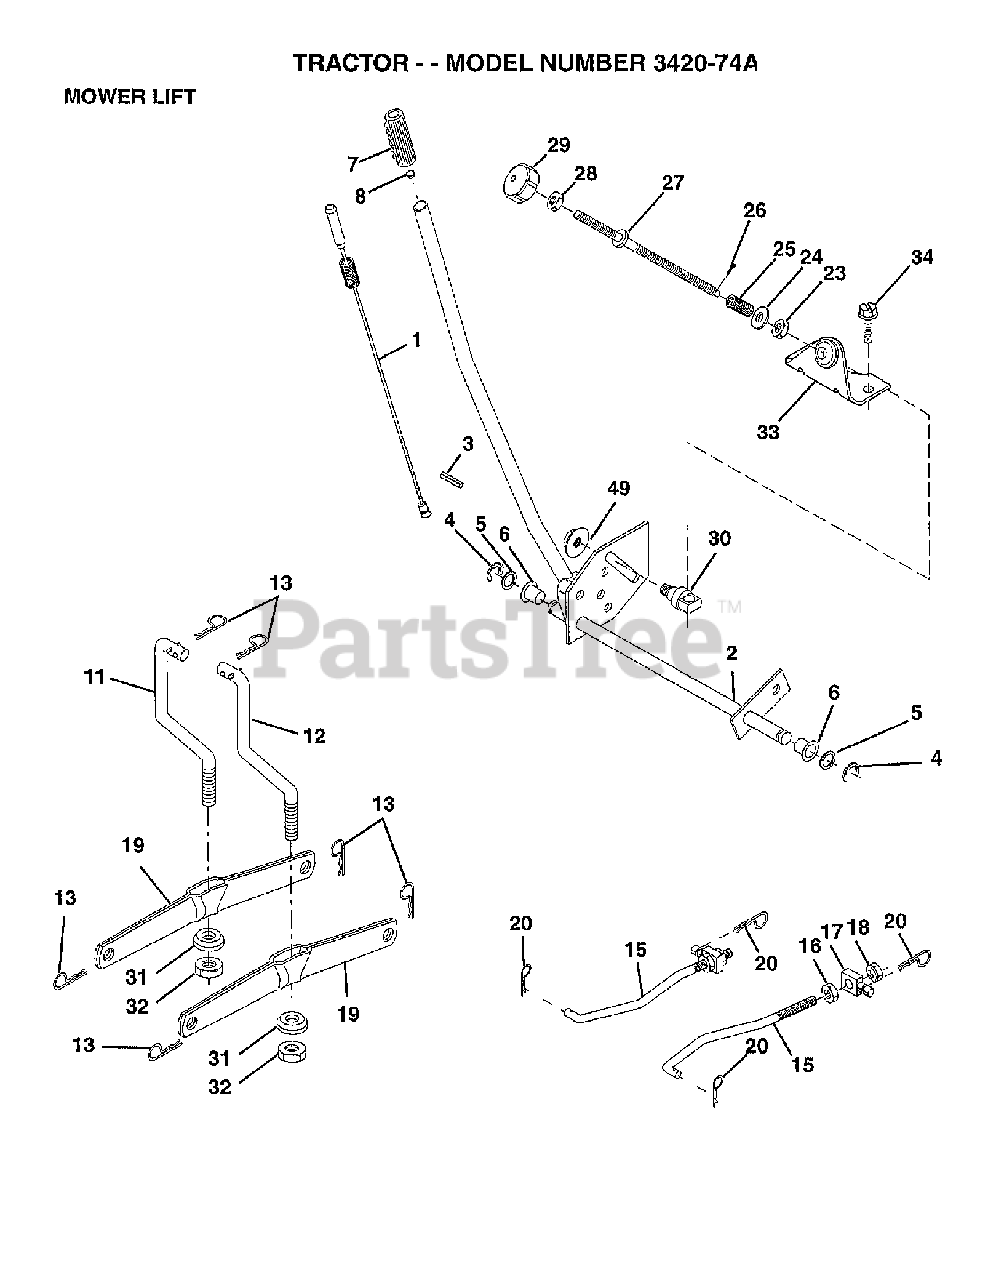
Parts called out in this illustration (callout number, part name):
1	WIRE ASM INNER W/ PLUNGER LT
3	PIN GROOVE
4	RETAINING RING LT
6	BEARING.NYLON
7	GRIP
8	PLUNGER BUT KIT
10	SPRING, COMP T
11	LINK LIFT LH
12	Lift Link Assembly, RH
13	RETAINER SPRING
15	FRONT LINK
16	NUT.HEX.JAM.1/2-13
18	NUT.LK.W/WSH.1/2.
19	ARM.REAR.SUSPENSION
20	SPRING RETAINER
24	WASHER
25	SPRING.COMP.INF.H
27	ROD.LIFT.ADJUSTABLE
28	NUT
29	KNOB INF 3/8-16
30	TRUNNION
32	NUT CROWNLOCK 3/8-24
49	Flange Hex Lock Nut, 3/8-16
50	NUT PUSH M
